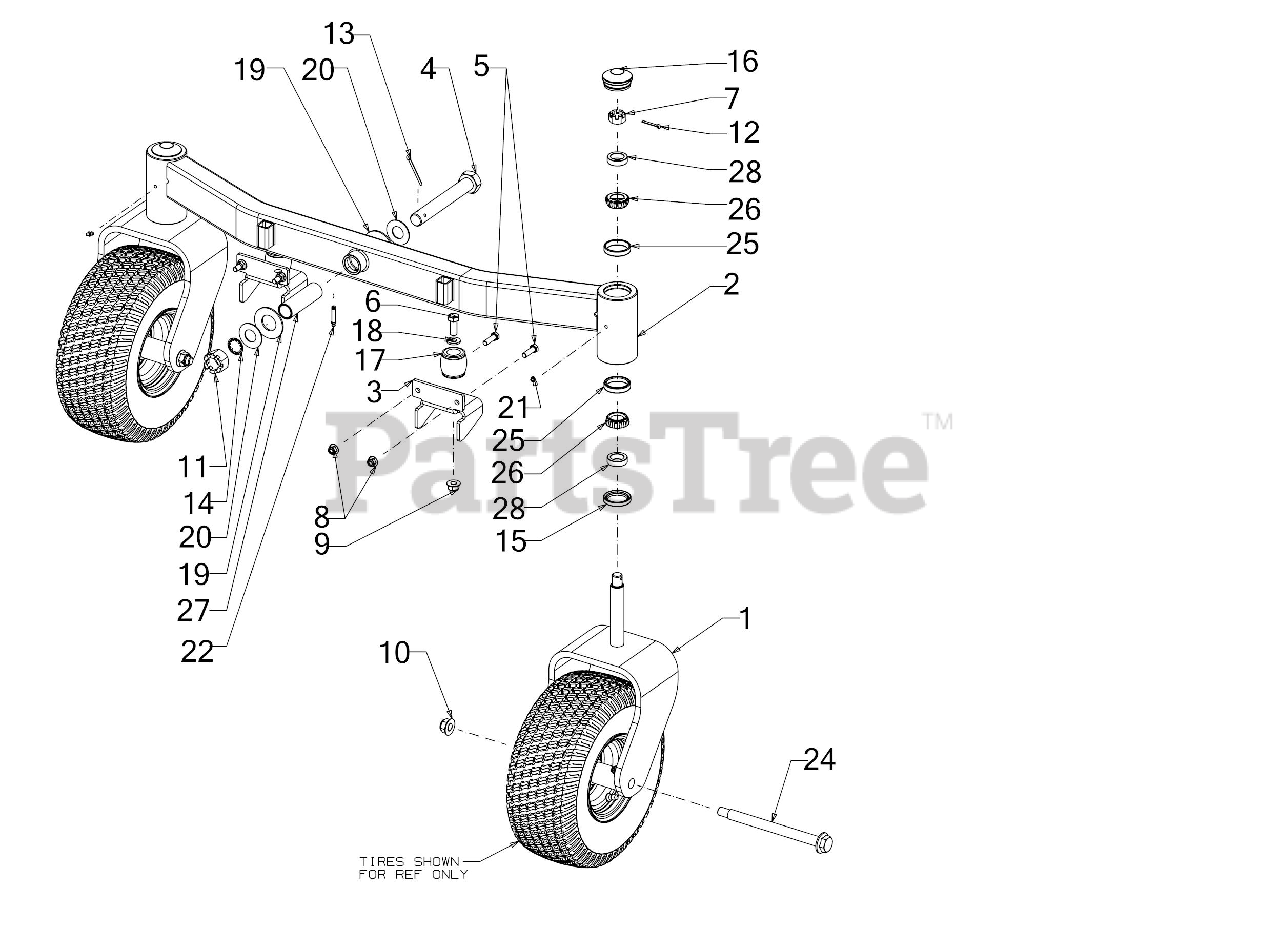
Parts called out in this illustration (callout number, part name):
1	FRONT CASTER ASSEMBLY (LAPBAR)
2	FRONT AXLE ASSEMBLY
3	AXLE BUMPER MOUNTING BRACKET
4	HEX HEAD SCREW 1-14 X 7 GR5
5	SCREW 3/8-16 x 1.25 GR5
6	SCREW 1/2-13 x 1.25 GR5
7	HEX NUT CASTLE 3/4-16
10	FLANGE LOCK NUT
11	CASTLE NUT 1.0-14 GR5
12	COTTER PIN-5/32 DIA
13	COTTER PIN
14	RETAINING RING
16	AXLE GREASE CAP
17	AXIAL BUMPER
18	FLAT WASHER .510 x 1.000 x .125
19	BELL WASHER 1.25ID x 2.5 x .180
20	FLAT WASHER 1.0 x 2.0 x .075
21	GREASE ZERT 1/4-28
22	GREASE FITTING
24	SHOULDER BOLT .750 X 8.175:5/8-11
25	BEARING CUP
26	BEARING CONE
